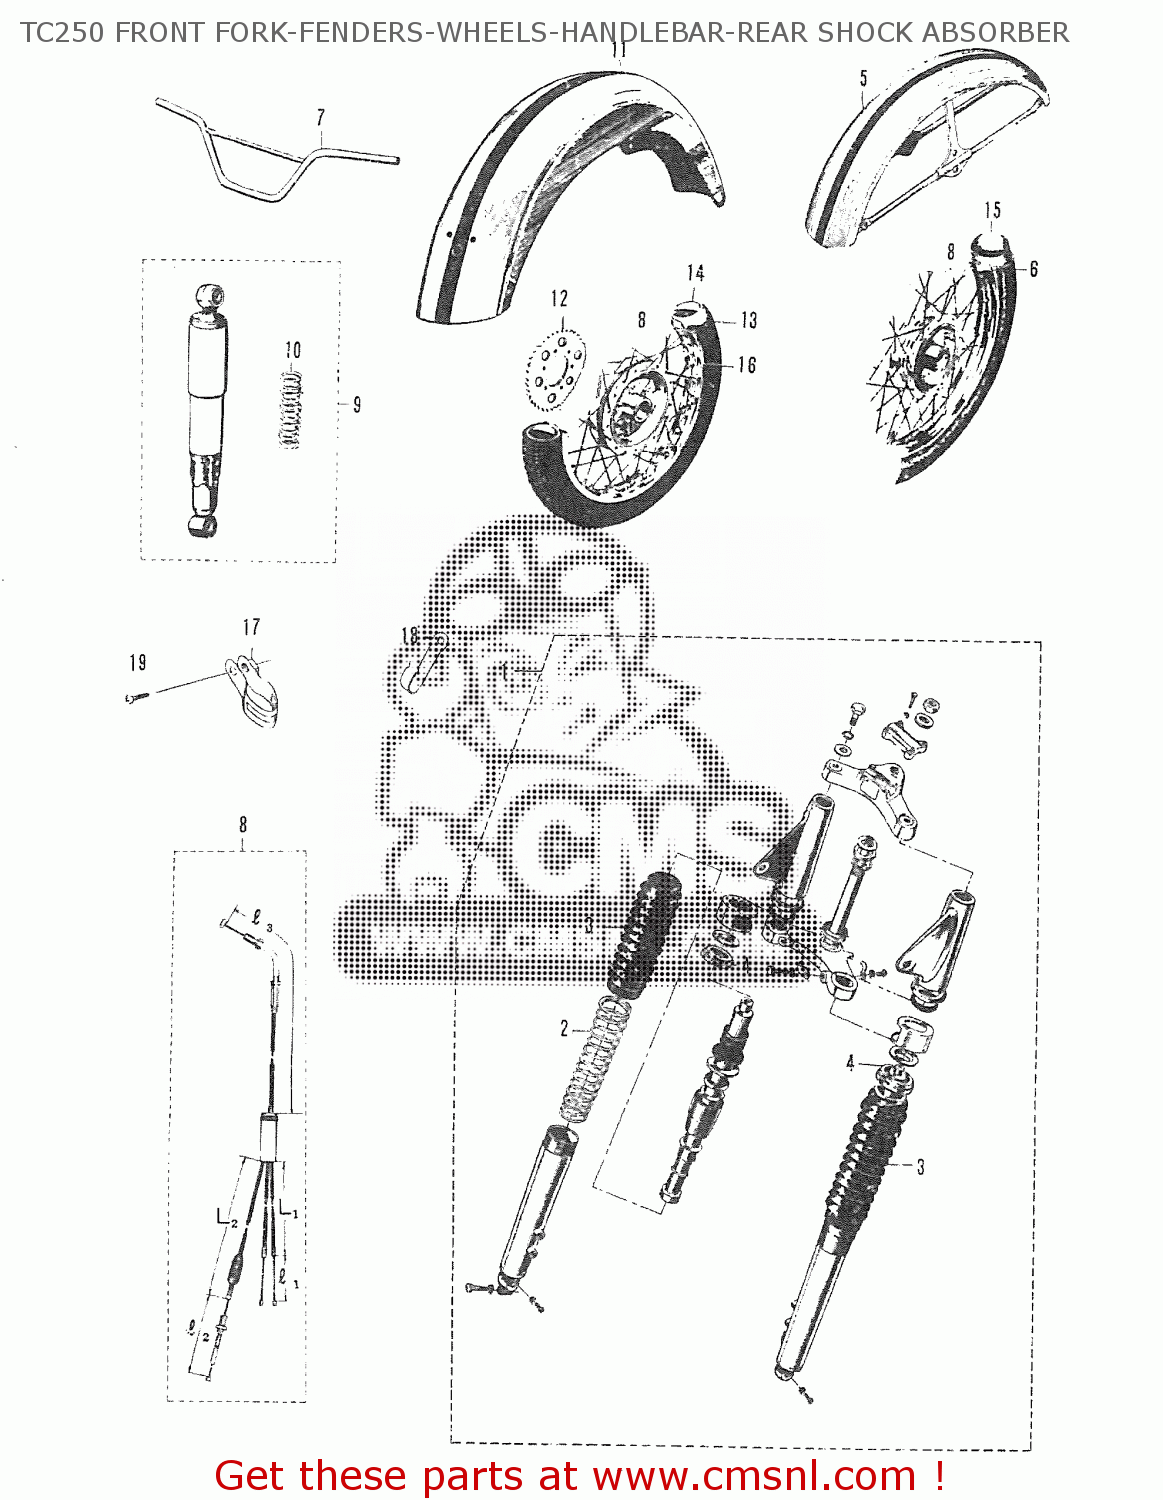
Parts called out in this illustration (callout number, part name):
1	FRONT FORK ASS'Y
2	SPRING,FRONT FORK
3	BOOT,SPRING COVER
4	BAND,FRONT FORK COVER
5	FRONT FENDER
6	FRONT TIRE
7	HANDLEBER
8	REAR WHEEL ASS'Y
9	ABSORBER ASSEMBLY,REAR SHOCK
10	SPRING
11	REAR FENDER
12	REAR SPROCKET
13	REAR TIRE
14	REAR INNER TUBE
15	TUBE ASSEMBLY,WHEEL,INNER
16	RIM,RR WHEEL
17	CABLE CLIP BAND
18	CLAMP
19	CROSS HEAD SCREW
